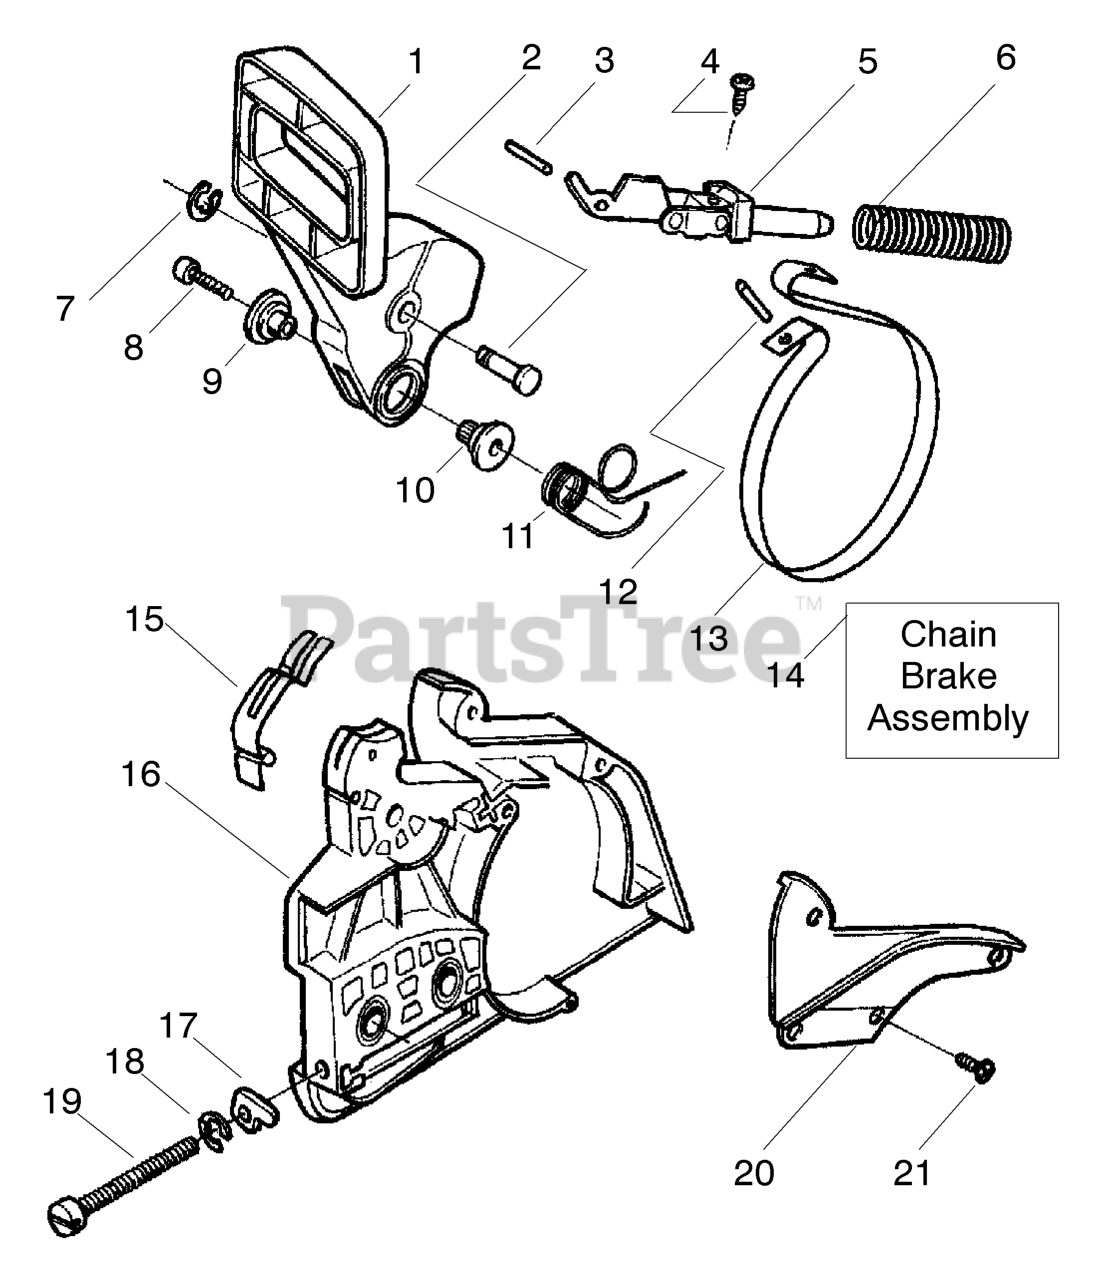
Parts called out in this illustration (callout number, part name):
4	SCREW
5	FRONT LINK ASSY
6	%COMPRESSION SPRING
9	JOURNAL, RIGHT
10	SHAFT PIVOT
11	SPRING,BRK HDL 36/41
13	BRAKE BAND
14	CHAIN BRAKE ASM.
15	SPRING-POSITION
16	CLUTCH COVER
17	ADJUST PIN,BAR 36/41
19	BAR ADJUSTING SCREW
20	CHAIN BRAKE COVER
21	SCREW
